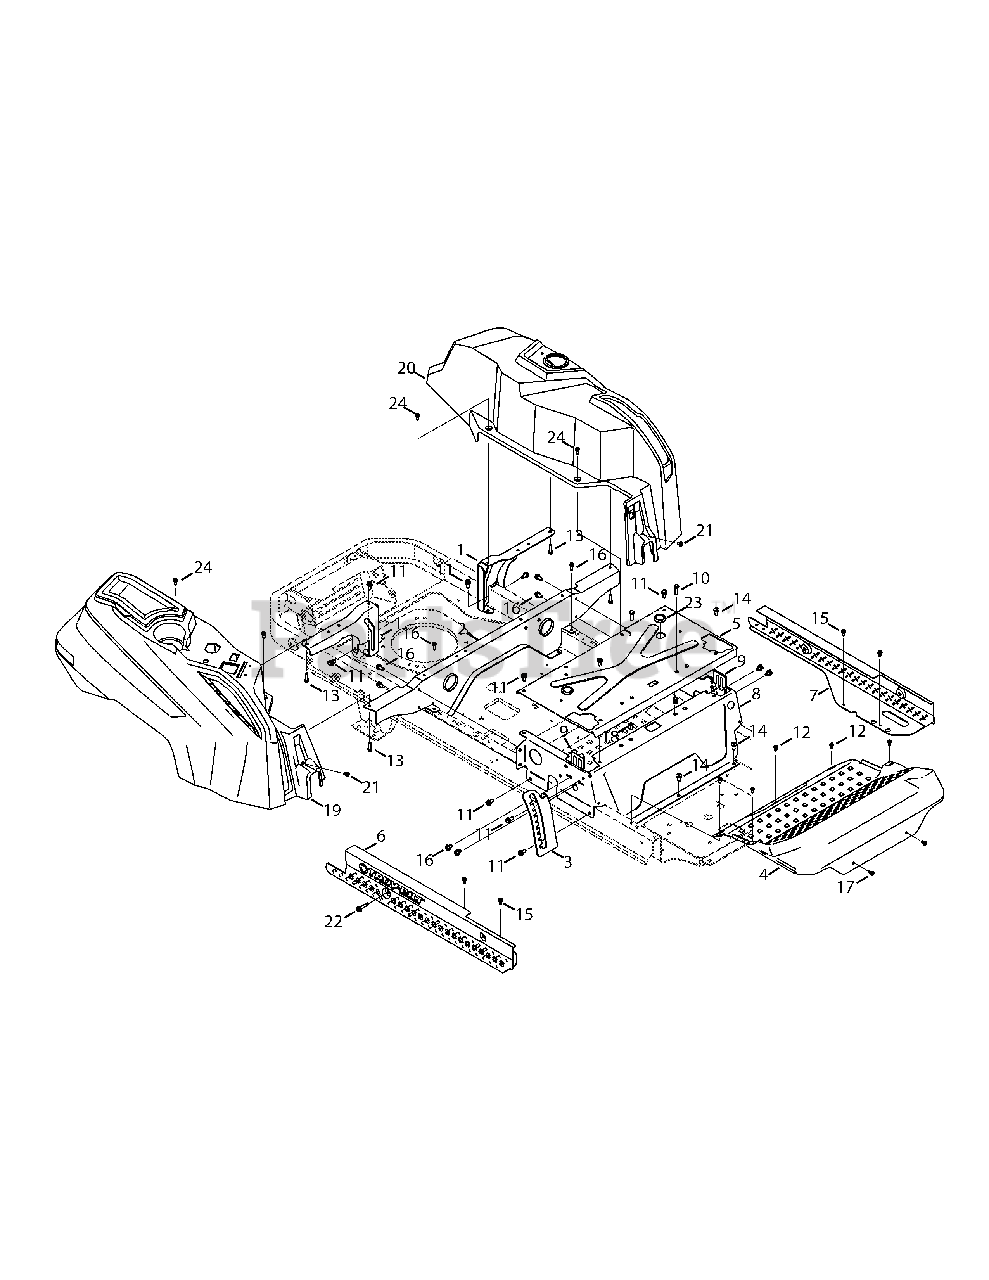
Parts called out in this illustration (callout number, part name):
1	Rear Tank Bracket
2	Rear Seatbox Brace
3	Height Index Bracket
4	Floor Board
5	Seatbox Plate
6	Frame Support, RH
7	Frame Support, LH
9	Lapbar Brace Bracket
10	Hex Cap Screw, 5/16-18 x 1.00
11	SCREW 5/16-18 x .750
12	Self Tapping Screw, 1/4-20 x .50
13	Hex Washer Screw, 5/16-14 x 1.00
14	Self Tapping Screw, 5/16-18 x .750
15	Hex Washer Screw, 1/4-20 x .500
16	Hex Washer Screw, 5/16-18 x .50
17	Screw, Self-Tapping, 5/16-18, 0.750
18	Nut, 5/16-18
19	RH Console
20	LH Console
21	TORX SHOULDER SCREW 1/4-20
22	Hex Washer Screw, 3/8-16 x 1.25
23	Button Plug
24	Shoulder Screw, .368 x .115, M6-1
